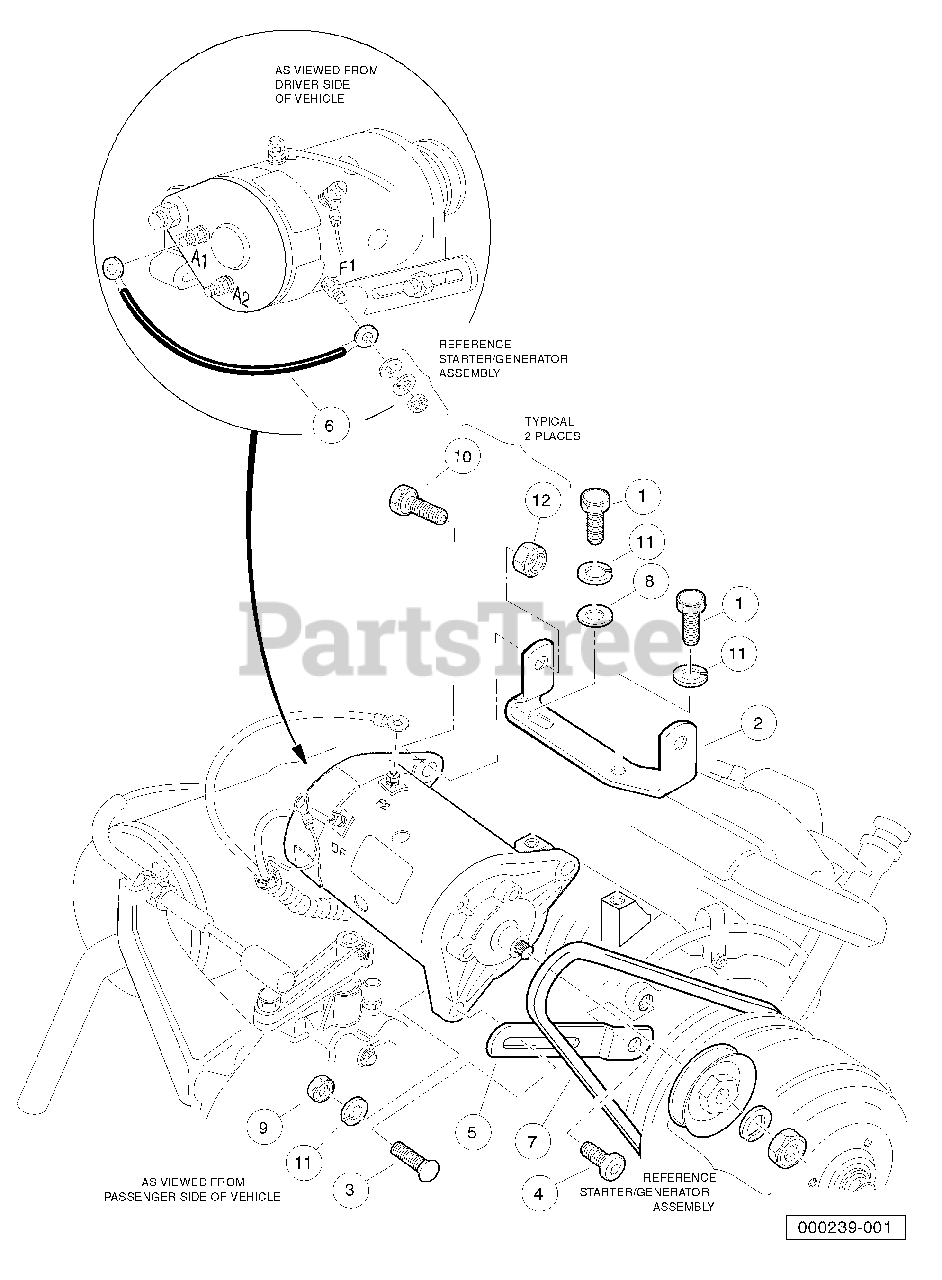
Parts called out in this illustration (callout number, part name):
1	Screw, M8-125 X 22 Hex-Head
2	Bracket, Starter/Generator Mounting
3	Bolt, Carriage, 5/16-18
4	Screw, M8-1.25 X 18mm Torx
5	Bracket, Starter/Generator Adjustment
6	Wire Assy, #6 Green
8	Washer, 5/16 Type A Flat
9	Nut, 5/16-18 Hex
10	Screw, Cap-hex Hd 3/8-16x1.25
11	Lockwasher, 5/16 Split
12	Locknut, 3/8-16 Hex
